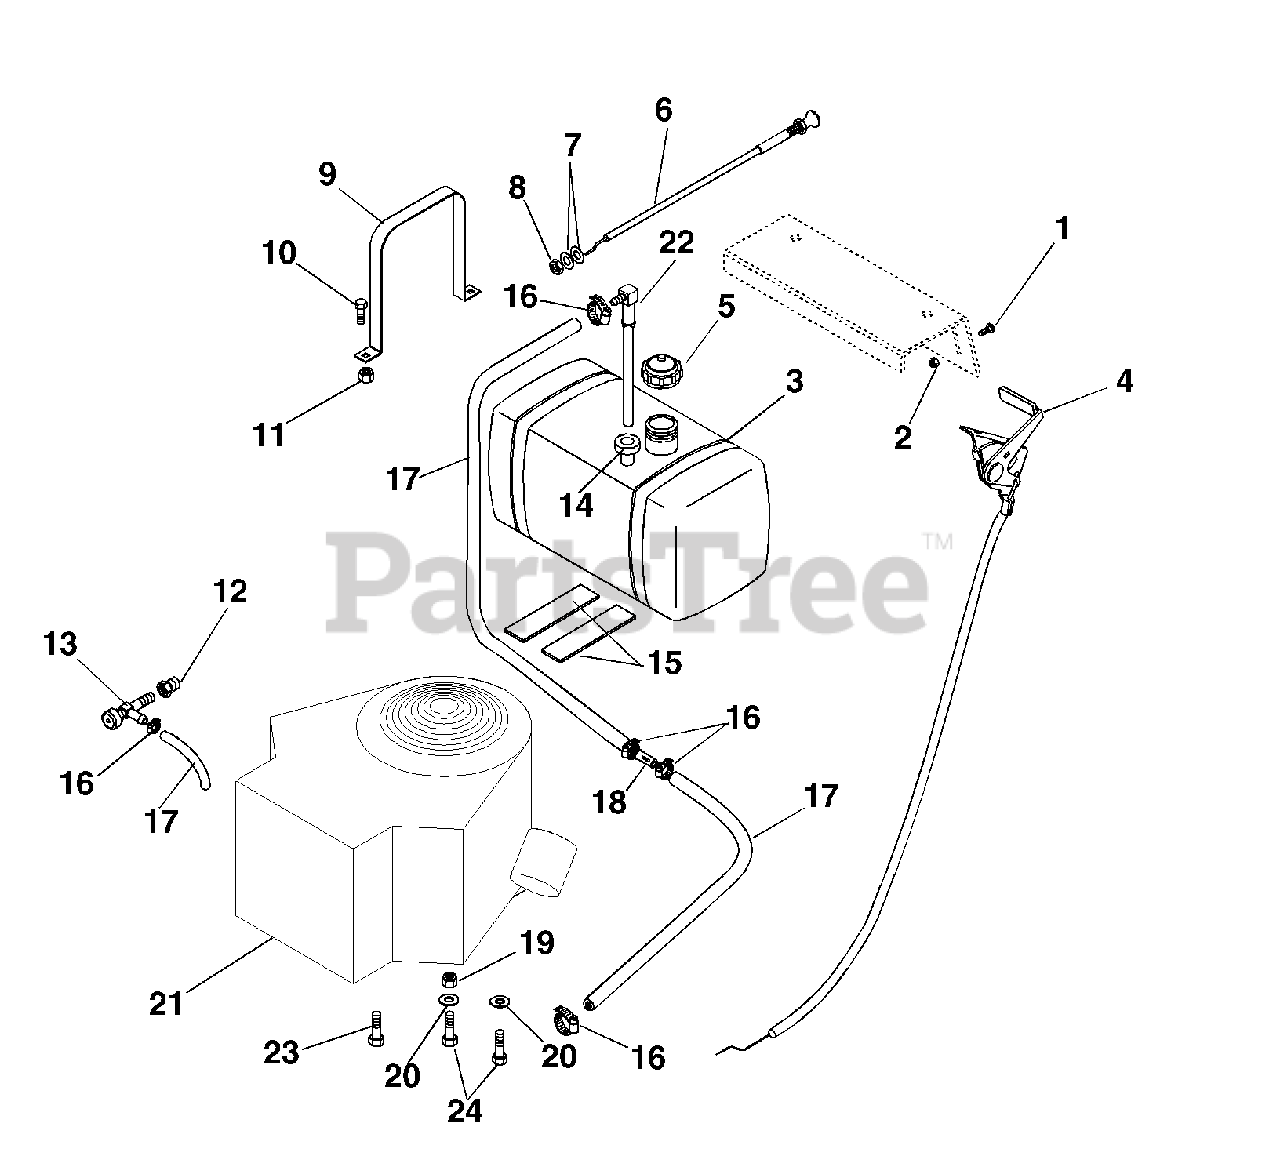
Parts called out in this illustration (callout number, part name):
1	SCR-MCH 10-32X.50 PHD
2	NUT-LK 10-32 NY YWZC
3	FUEL TANK
4	THROTTLE CONTROL
5	CAP, FUEL TANK
6	CONTROL,CHOKE
7	WSHR-FL-STL.406X.812X.065 YWZ
8	NUT-JAM .375-24 YWZC
9	TANK STRAP FOR 4.5 G FUEL TANK
10	BLT-HEX .25-20X.63
11	NUT-LK-NYL .250-20 YWZC
12	ADAPTER, OIL DRAIN
13	ADAPTER, OIL DRAIN
14	BSHG-FLG .375 X 1.062 X .625 R
15	PAD, GAS TANK
16	HOSE CLAMP
17	GAS LINE-BULK 1/4" I.D.
18	FILTER,FUEL
19	@NUT-LK-CTR .31-18 YWZC
20	@WSHR-FL-STL.344X.688X.065YWZC
21	ENGINE BRIGGS 16HP TWIN
22	FITTING, TANK
23	@BLT-HEX .31-18X1.75 GR5 YWZC
24	@BLT-HEX .31-18X1.50 GR5 YWZC
